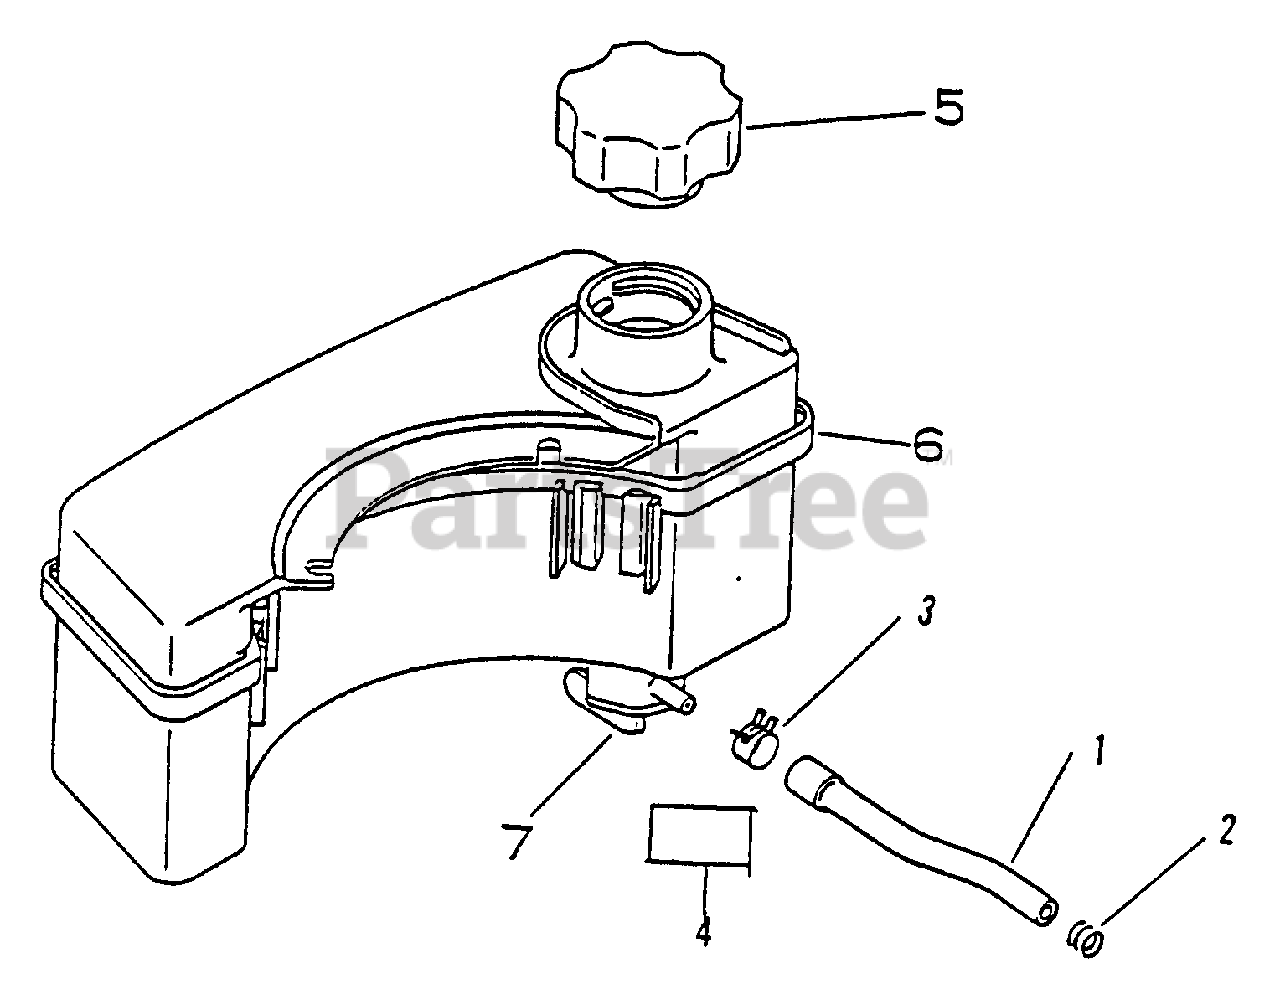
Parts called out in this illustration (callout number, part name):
1	PIPE - FUEL
2	CLIP
3	CLIP
4	LABEL - FUEL COCK
5	CAP, FUEL
6	FUEL TANK ASSY
7	FUEL VALVE ASSY
